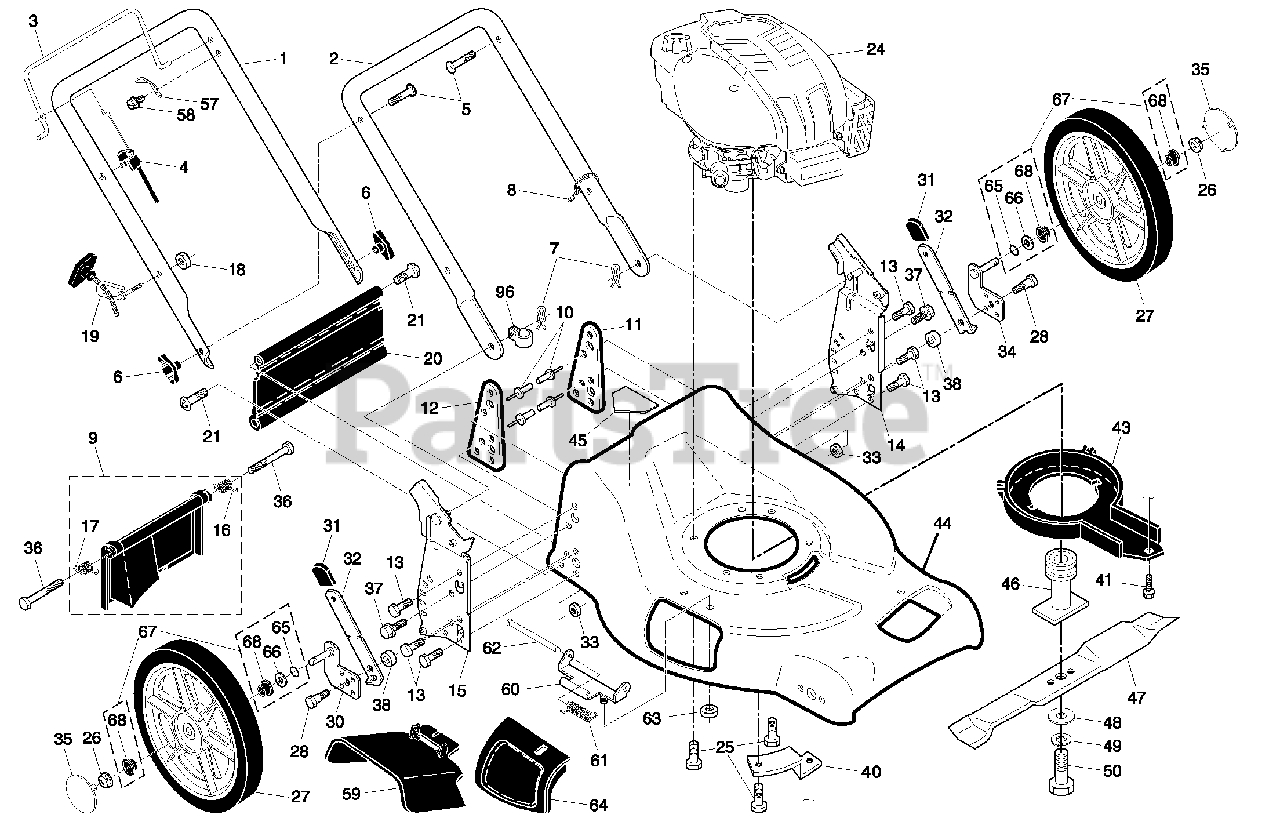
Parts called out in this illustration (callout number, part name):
1	Upper Handle
2	Lower Handle
3	Control Bar
4	Engine Zone Control Cable
5	Handle Bolt
6	Handle Knob
7	Hairpin Cotter
8	Wire Tie
9	Kit, Rear Door
10	Pop Rivet
11	Support Bracket, LH
12	Support Bracket, RH
13	Screw 1/4-20 x 5/8
14	Handle Bracket Assembly, LH
15	Handle Bracket Assembly, RH
16	Spring, Rear Door, LH
17	Spring, Rear Door, RH
18	Keps Locknut 1/4-20
19	Rope Guide
20	Rear Skirt
21	Hinge Screw 1/4-20 x 1-1/4
22	Pulley, Engine
23	Key, Hi-Pro
25	Screw, Hex Head, Threaded, Rolled 3/8-16 x 2
26	Nut, Hex, Flangelock 3/8-16
27	Wheel & Tire Assembly, Rear, 14"
28	Bolt, Shoulder 5/16-18
30	Axle Arm Assembly, Rear, RH
31	Selector Knob
32	Selector Spring
33	Nut, Hex, Nylock 5/16-18
34	Axle Arm Assembly, Rear, LH
35	Hubcap
36	Bolt, Rear Door
37	Thread Cutting Screw w/Sems 5/16-18 x 3/4
38	Washer, Flat .34 x 1.38
40	Mounting Bracket, Debris Shield
41	Screw, Debris Shield
43	Debris Shield
45	Danger Decal
46	Blade Adapter
47	Blade, 21"
48	Hardened Washer
49	Helical Washer 3/8
50	Blade Bolt, Hex Head, Grade 8
57	Upstop Bracket
58	Screw #10-24 x 1/2
59	Discharge Deflector
60	Hinge Bracket
61	Spring, Torsion
62	Rod, Hinge
63	Nut, Hex
64	Mulcher Door
65	O-Ring
66	Washer, Flat 3/8
67	Kit, Bushing, High Wheel
68	Bushing, Nylon, Black
96	Clip, Cable
96	Operator's Manual, English
96	Operator's Manual, French
96	Repair Parts Manual, English / French
